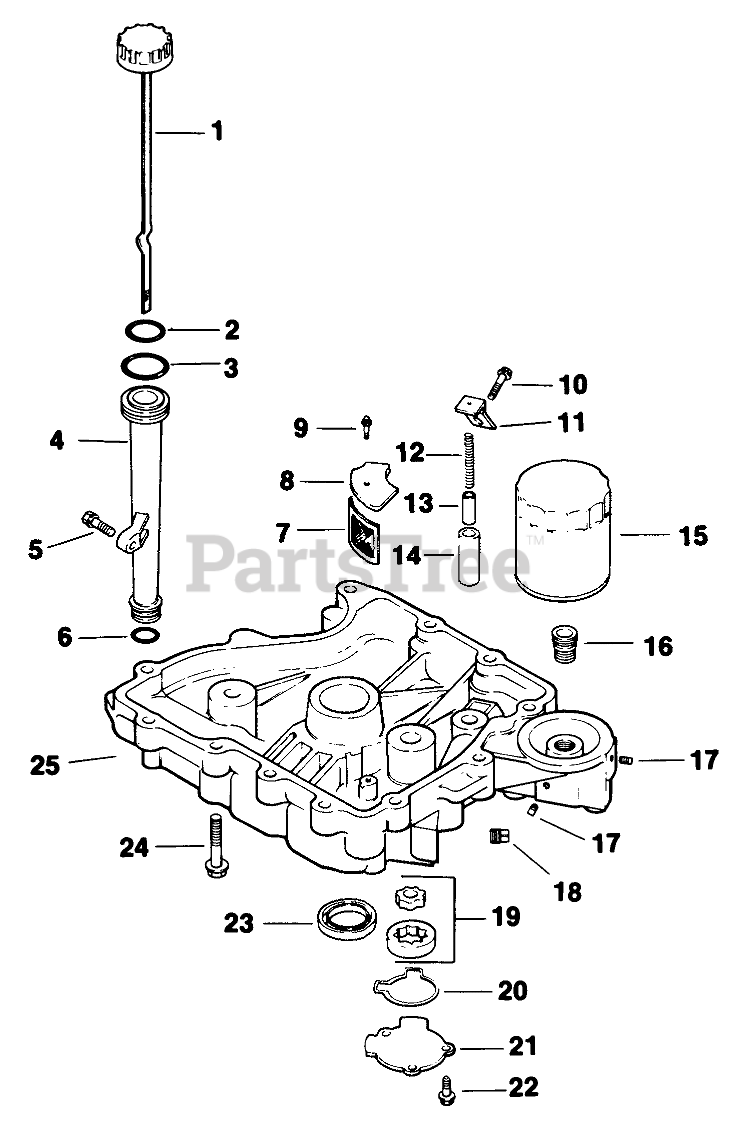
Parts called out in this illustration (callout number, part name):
1	Dipstick INC 2-3
2	"O"Ring
3	"O"Ring-Upper Tube
4	Tube-Oil Fill
5	Screw
6	"O"Ring
7	Screen-Oil Pickup
8	Cover-Oil Screen
9	Screw
10	Screw
11	Bracket-Relief Valve
12	Spring-Relief Valve
13	Piston-Relief Valve
14	Body-Relief Valve
15	Filler-Oil
16	Adapter-Oil Filler
17	Plug-SH 1/8
18	Plug
19	Pump-Oil
20	"O" Ring-Oil Pump
21	Cover-Oil Pump
22	Screw
23	Seal-Oil
25	Pan-Oil
